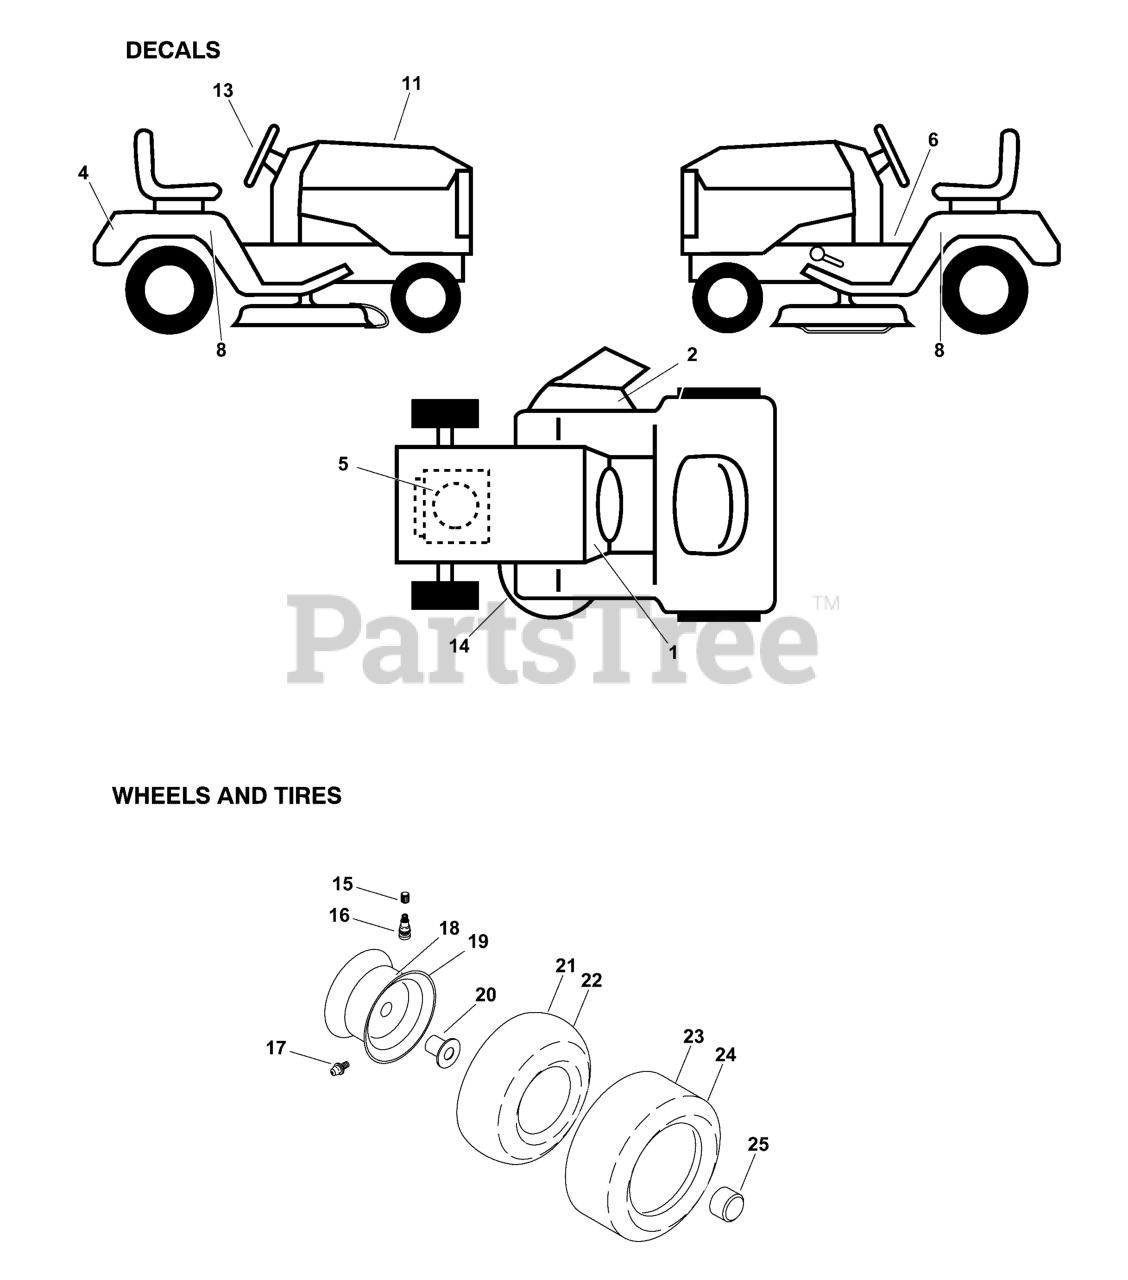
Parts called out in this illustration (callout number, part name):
1	DECAL, Snowflake Dash
2	DECAL, Keep Hand Away
4	DECAL, Fender
5	DECAL, Engine H.P.
6	Decal, Fender Operator's
8	DECAL, Fender LH/RH
11	DECAL, Replacement
13	Decal, Steering Wheel
14	Decal, Mower Schematic
15	Cap, Valve, Tire
16	Stem, Valve
17	FITTING, Grease
18	Rim Asm 6" Front Service
19	Rim Asm 8" Rear Service
20	BEARING, Flange
21	Tube, Front
22	Tube, Rear
23	TIRE, Front 15 x 6-6
24	TIRE, 20 X 10-8 Rear
25	Cap, Axle
